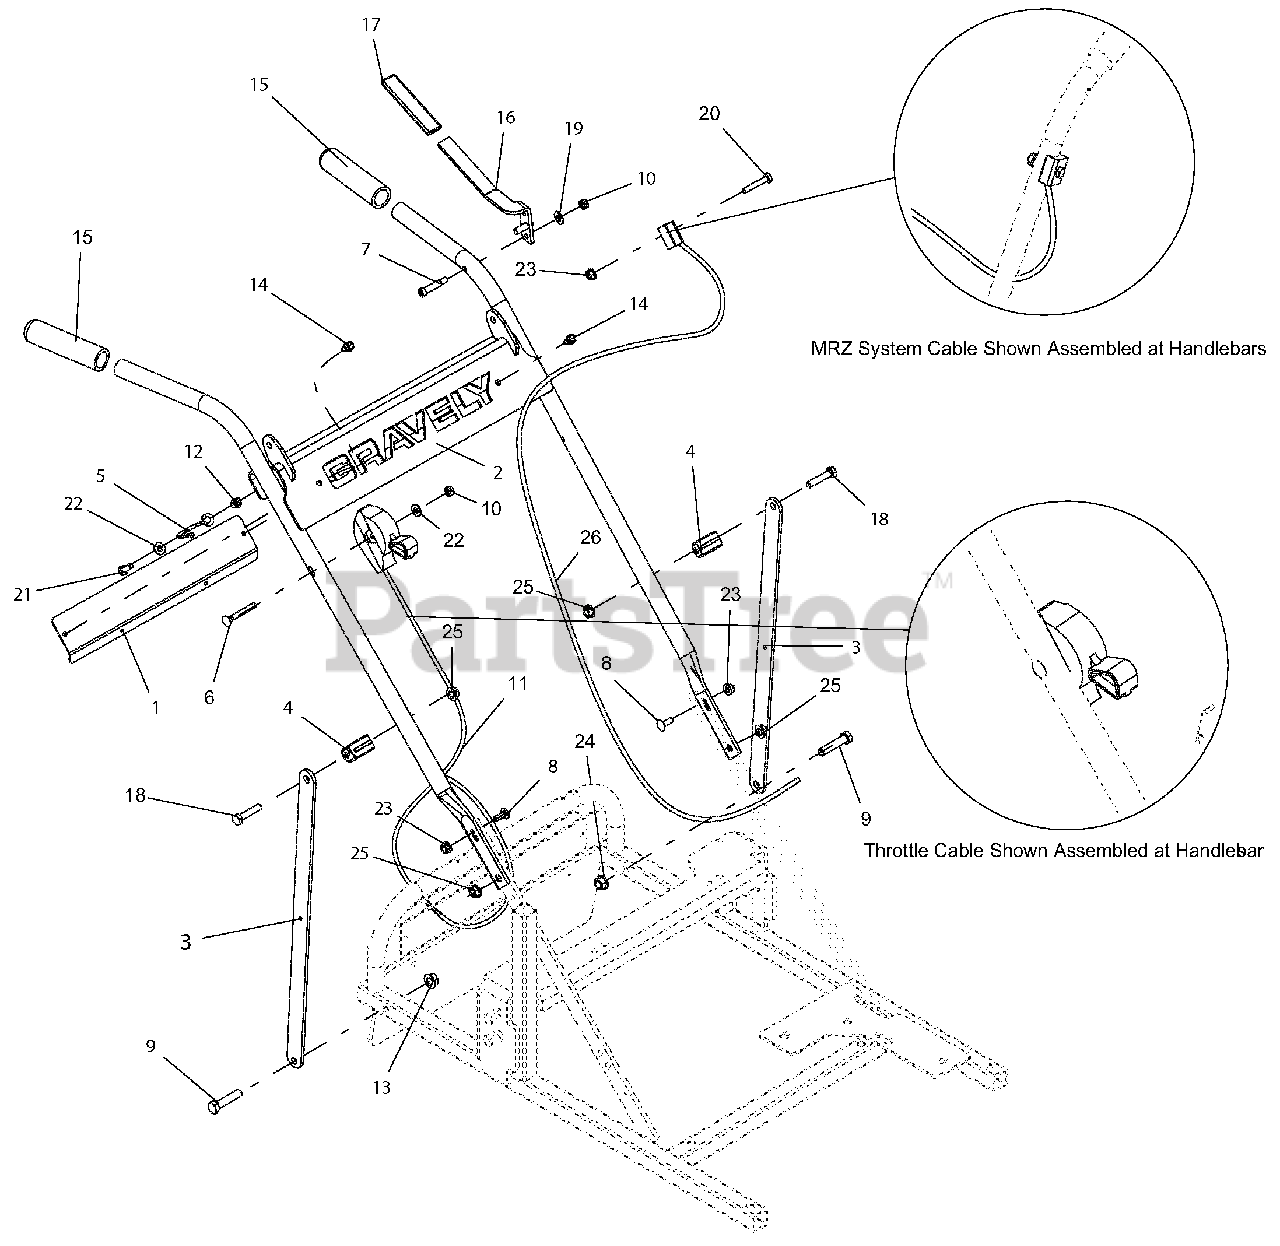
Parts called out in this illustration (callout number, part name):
1	BACKER, GRAVELY
2	WLDMT, HANDLEBAR HW MOWER (RED)
3	BRACE, HANDLEBAR , HWM (RED)
4	SEAT CLAMP (BLACK)
5	GUIDE, PULLCORD
6	BLT, RDHDXLSQNK .25-20X2.0 G5YZ
7	SCR, SHLDR .25-20X1.00- YWZC
8	BLT-RDHDSQNK .25-20X.75 G5 YWZC
9	BLT-HEX .38-16X1.75 GR5 YWZC
10	NUT-LK-CTR .25-20 YWZC
11	CABLE, THROTTLE (NON-CHOKING)
12	NUT-LK-NYL .250-20 YWZC
13	NUT, LK-TOP-FLG .38-16 YWZC
14	SCR-TAP .25-20X.50 HWH TR YWZ
15	GRIP, BLACK 7/8ID
16	WLDMT, OPC LEVER, HW MOWER (BLACK)
17	GRIP, MZR/MOMENT SP 7/8X3/4X4
18	BLT-HEX .31-18X1.50 GR5 YWZC
19	WSHR-FL-STL.344X.688X.065YWZC
20	BLT-HEX .25-20X1.50 GR5 YWZC
21	BLT-HEX .25-20X.75 GR5 YWZC
22	WSHR-FL-STL.281X.62X.065 YWZC
23	NUT, LK-TOP-FLG .25-20 YWZC
24	NUT, LK-TOP-FLG .38-16 YWZC
25	NUT, LK-TOP-FLG .312-18 YWZC
26	CABLE, MRZ SYSTEM 2
